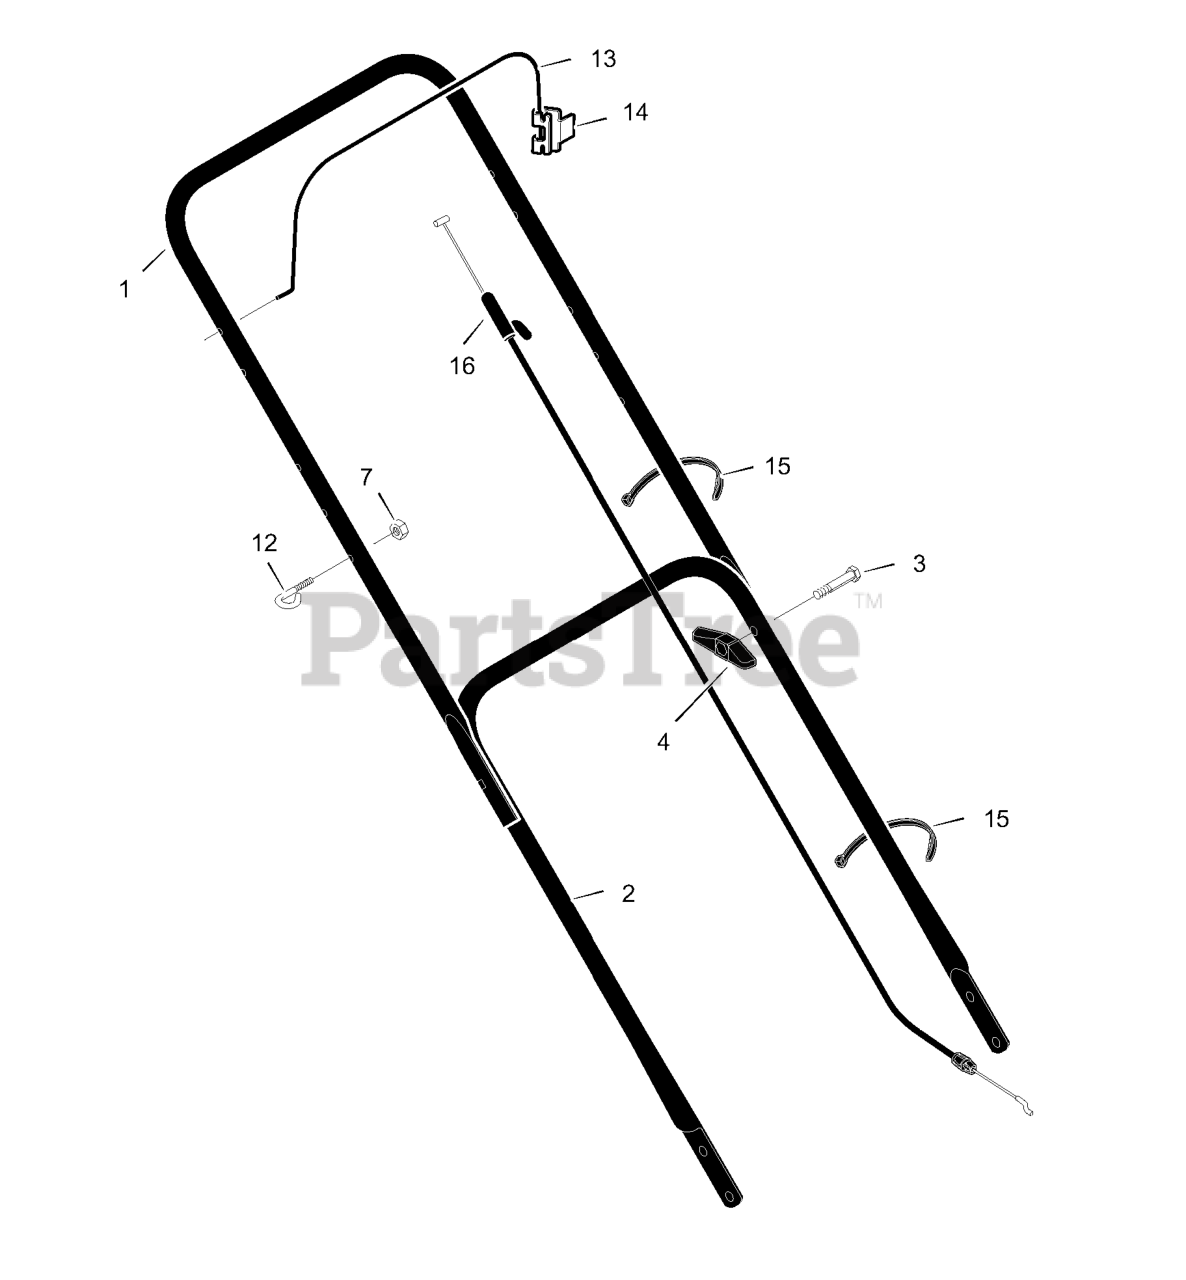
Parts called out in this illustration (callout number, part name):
1	Handle, Upper (Black)
2	Handle, Lower (Black)
4	Knob, Plastic
7	Locknut
12	Guide, Rope
13	Engine Stop Lever
14	Bracket, Stop Lever
15	Fastener, Cable
16	Engine Stop Cable
